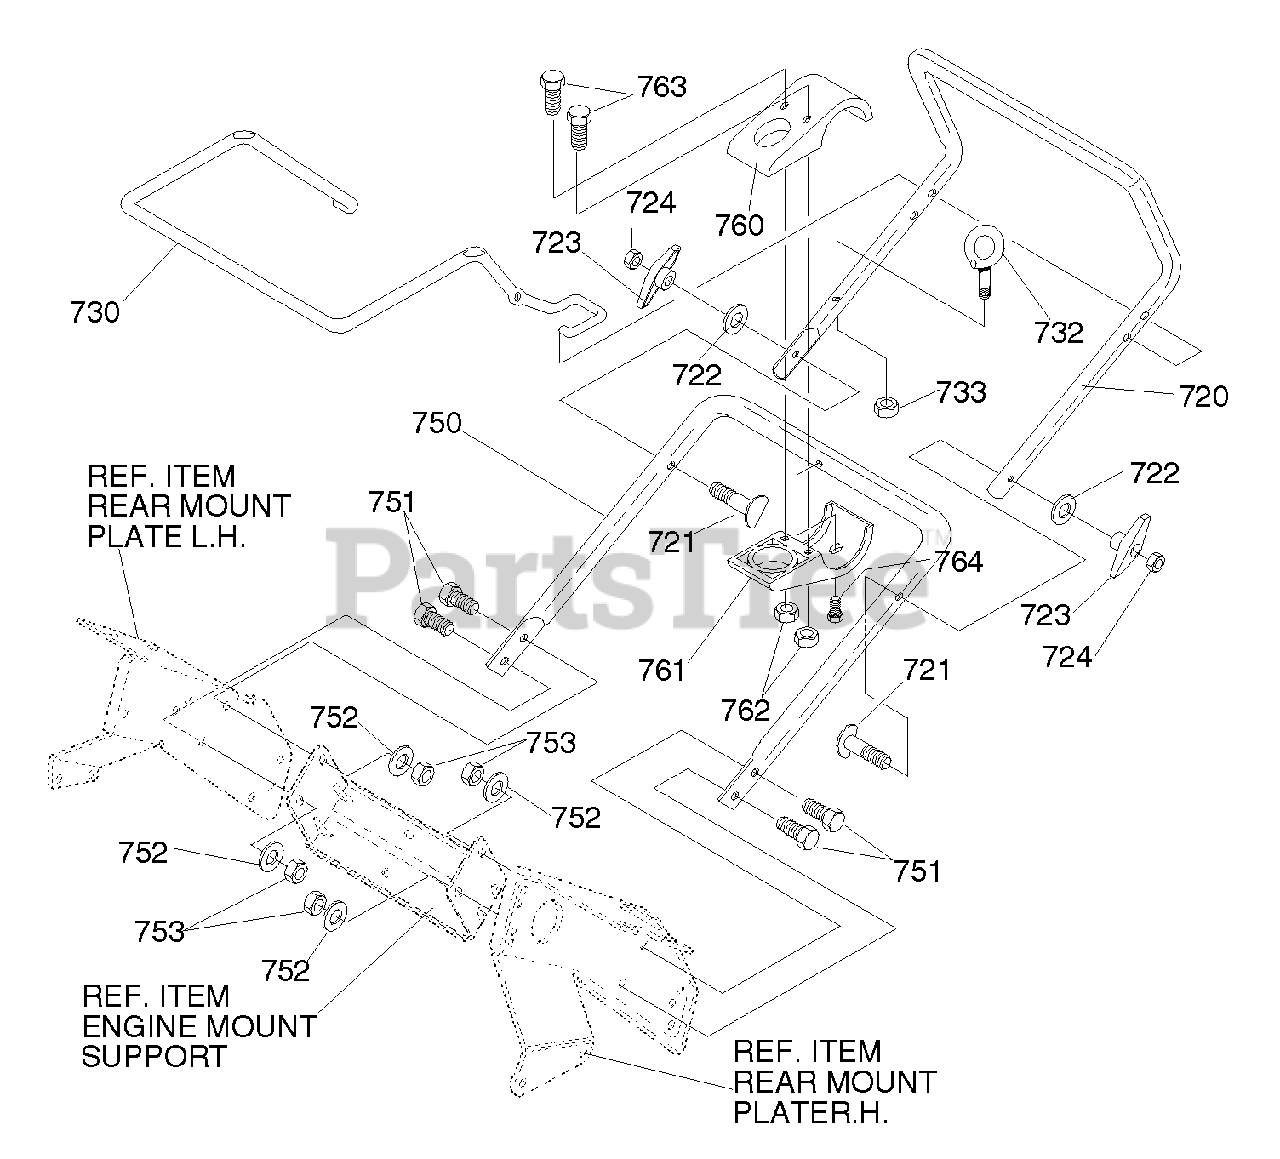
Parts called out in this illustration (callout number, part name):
720	HANDLE & FOAM ASSY
721	BOLT, 5/16-18 X 2.00 CUH
722	FORMED WASHER
723	KNOB, T 2/BLADE
724	NUT, 5/16-18 REGHEX
730	CONTROL DRIVE BAR
732	ROPE GUIDE
733	NUT, 5/16-18 RGHXCTRLK
750	LOWER HANDLE
751	SCREW 5/16-18 X .75
752	FLATWASHER
753	NUT, 5/16-18 REGHXCTRLK
760	BRKT, HALF CHUTE CRANK
761	BRKT, HALF CHUTE CRANK
762	NUT #10-24 HEXNYLLK
763	SCREW #10-24 X 1.00
764	SCREW 1/4-20 X .63 TAP.
